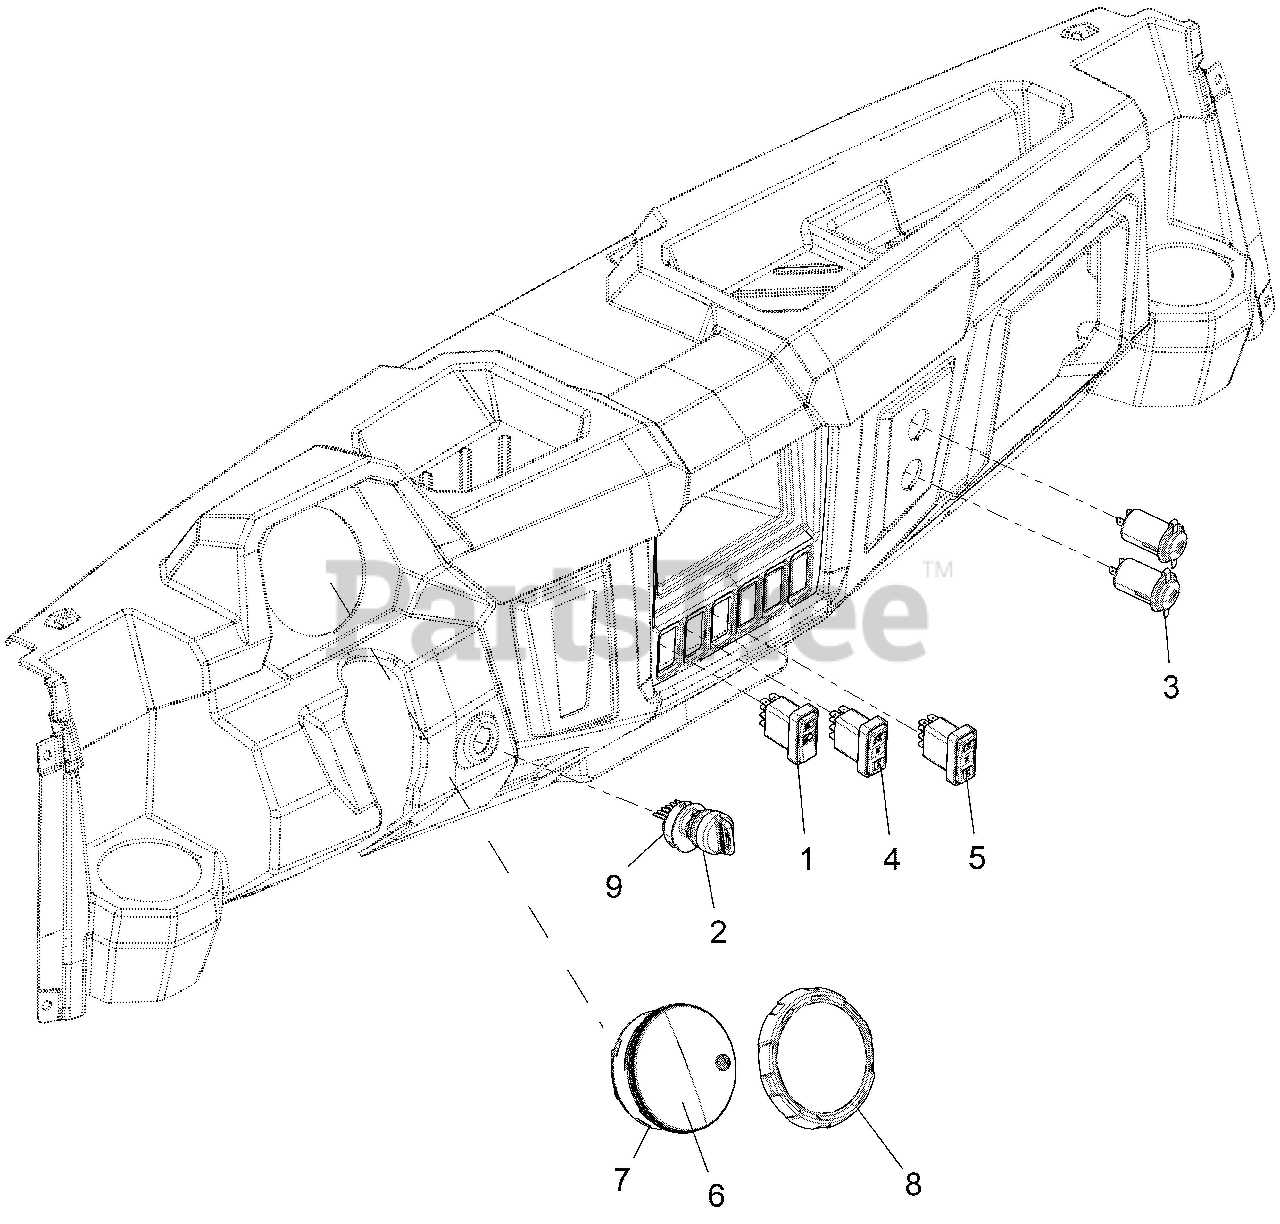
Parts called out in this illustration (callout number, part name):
1	SWITCH-HEADLIGHT
2	SWITCH,KEY,ARIENS
3	RECEPTACLE-POD MNT,12 VOLT
4	SWITCH-AWD
5	SWITCH-BOX LIFT,MOMENTARY
6	ASM-CLSTR,CPIA3,OSPS,ESIN
7	MOUNT-RUBBER,INSTR. CLUSTER
8	BEZEL-INSTRUMENT CLUSTER
9	SPACER, KEY, SWITCH
